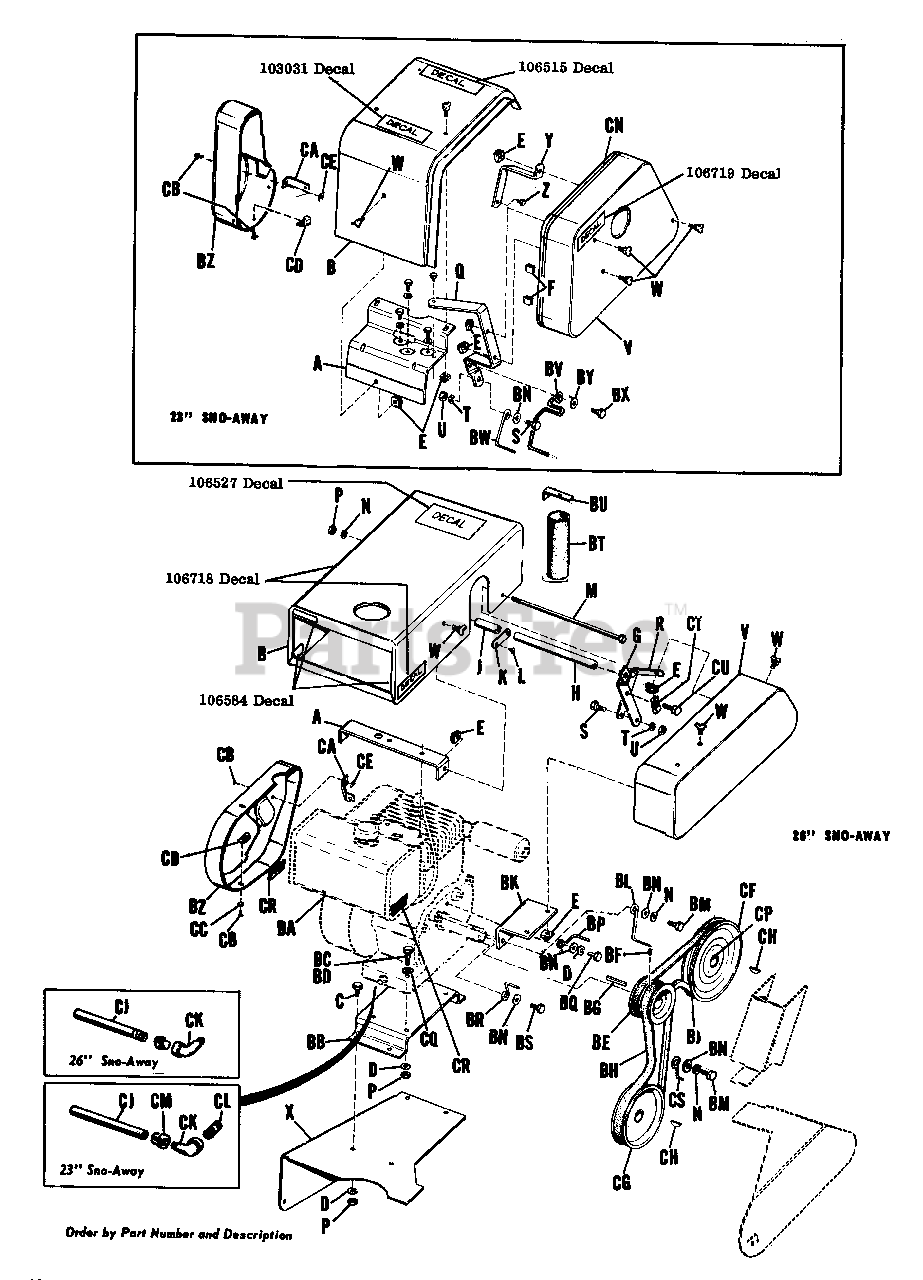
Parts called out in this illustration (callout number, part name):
A	Hood Support
B	Hood Assembly
E	Tinnerman Nut, #C31280-5618-1
F	Speed Clip
Q	Belt Guard Support
S	Hex Capscrew, 3/8"-16 x 7/8"
T	Lock Washer, 5/16"
U	HexNut, Full, 5/16"-18
V	Belt Guard Assembly
W	Thumb Screw
X	Side Cover, RH
Y	Belt Guard Bracket
Z	Screw,Rec. Hex. Hd. Self-Tapping, 1/4"-20 x 3/8" lg.
BD	Hex Capscrew, 5/16"-18 x 1-3/4" lg.
BE	Engine Pulley
BF	Set Screw, Cup Pt., Socket Hd., 5/16"-18 x 3/8" lg.
BG	Key
BH	V-Belt (Rotor Drive)
BJ	V-Belt (Transmission Drive)
BN	Plain Washer, 5/16"
BV	Belt Stop
BX	Hex Capscrew, 1/2"-20 x 1" lg.
BY	Lock Washer, Int. Shakeproof, 1/2"
BZ	Cover, Air Cooling
CA	Cover Bracket
CB	Screw, Self-Tapping #10 x 1/2" lg.
CD	Speed Nut, Special
CE	Speed Nut
CF	Pulley, Transmission Drive
CH	Key, Woodruff
CJ	Tube, Oil Filler
CK	Street Elbow, 90ø
CN	Strip, White
CP	Screw, Set
